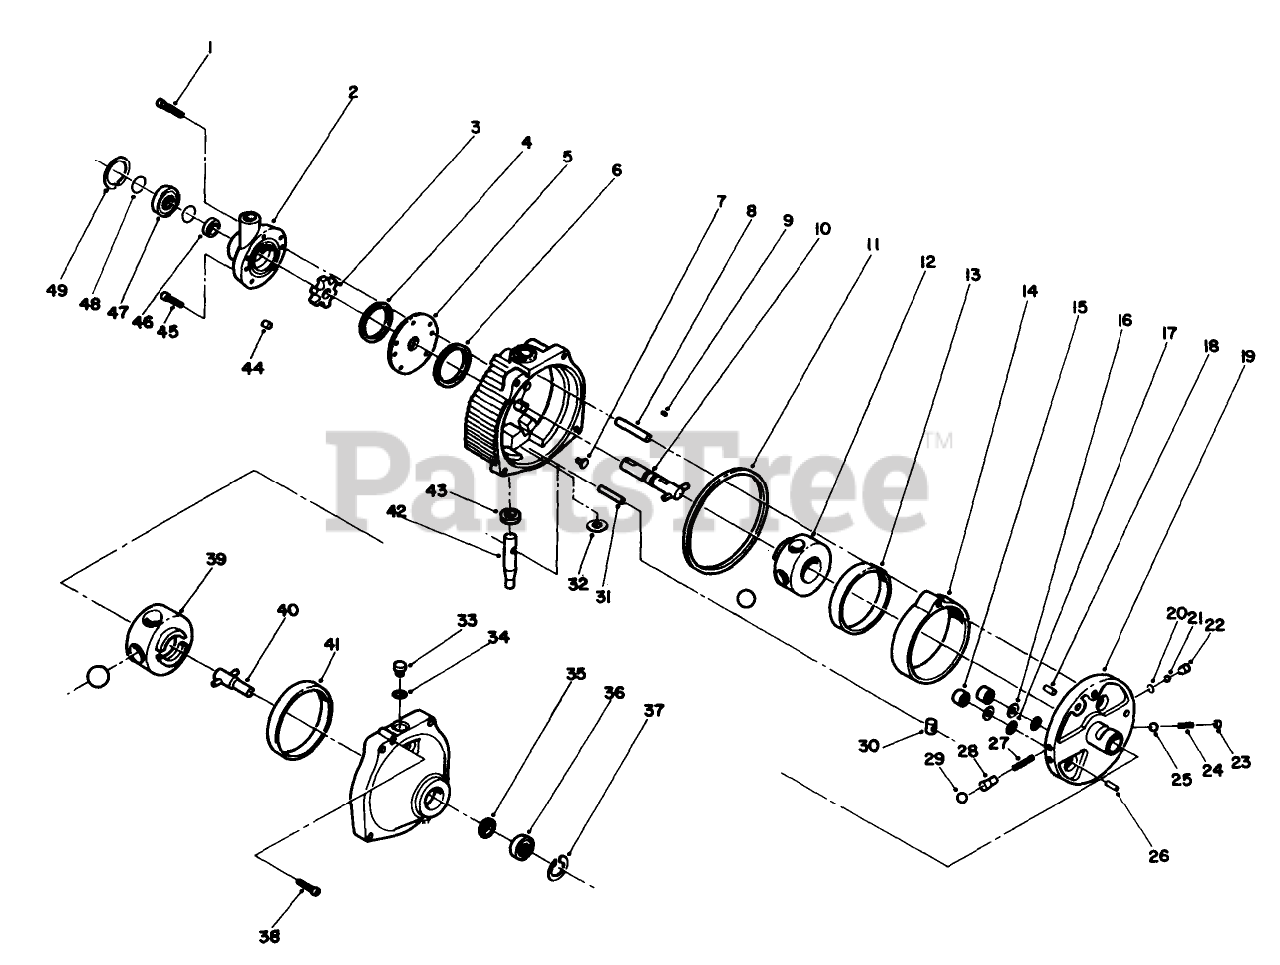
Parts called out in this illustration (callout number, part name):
1	CAPSCREW
2	CHARGE PUMP
3	CARRIER
5	PLATE
7	BUTTON
12	ROTOR
13	Pump Race
14	CAM RING ASM
15	PISTON
17	O-RING
19	PINTLE
24	SPRING
27	SPRING
30	INSERT
31	Dowel
32	Control Shaft Washer
33	PLUG ASM
34	O-RING
39	ROTOR
42	SHAFT KIT
45	SCREW-HH
46	SEAL-OIL
47	BEARING
